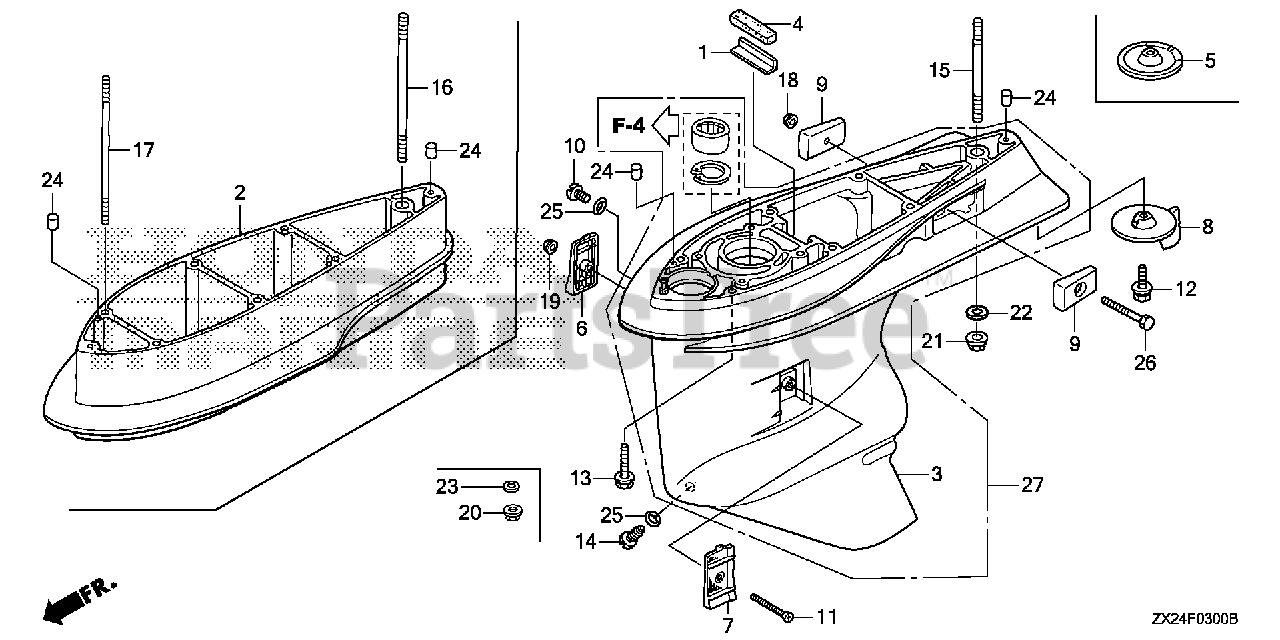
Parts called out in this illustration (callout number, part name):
1	PLATE, RUBBER SETTING
2	SEPARATOR, EXTENSION *NHB14M* (AQUA MARINE SILVER METALLIC)
2	SEPARATOR, EXTENSION *NH565* (GRAND PRIX WHITE)
3	CASE, GEAR *NHB14M* (AQUA MARINE SILVER METALLIC)
3	CASE, GEAR *NH565* (GRAND PRIX WHITE)
4	GROMMET, GEAR CASE
5	COVER, GEAR CASE *NHB14M* (AQUA MARINE SILVER METALLIC)
5	COVER, GEAR CASE *NH565* (GRAND PRIX WHITE)
6	SCREEN, R. WATER
7	SCREEN, L. WATER
9	METAL, ANODE
10	BOLT, OIL CHECK
11	SCREW, FLAT (5X55)
12	BOLT-WASHER (10X32)
14	BOLT, DRAIN PLUG
16	BOLT, STUD (12X170)
17	BOLT, STUD (10X170)
18	NUT, SELF-LOCK (6MM)
19	NUT, SELF-LOCK (5MM)
20	NUT, SELF-LOCK (10MM)
21	NUT, SELF-LOCK (12MM)
22	WASHER, PLAIN (12MM)
23	WASHER, PLAIN (10MM)
24	PIN, DOWEL (6X10)
25	O-RING (6.9X1.45)
26	BOLT, HEX. (6X55)
27	CASE, GEAR *NHB14M* (AQUA MARINE SILVER METALLIC)
